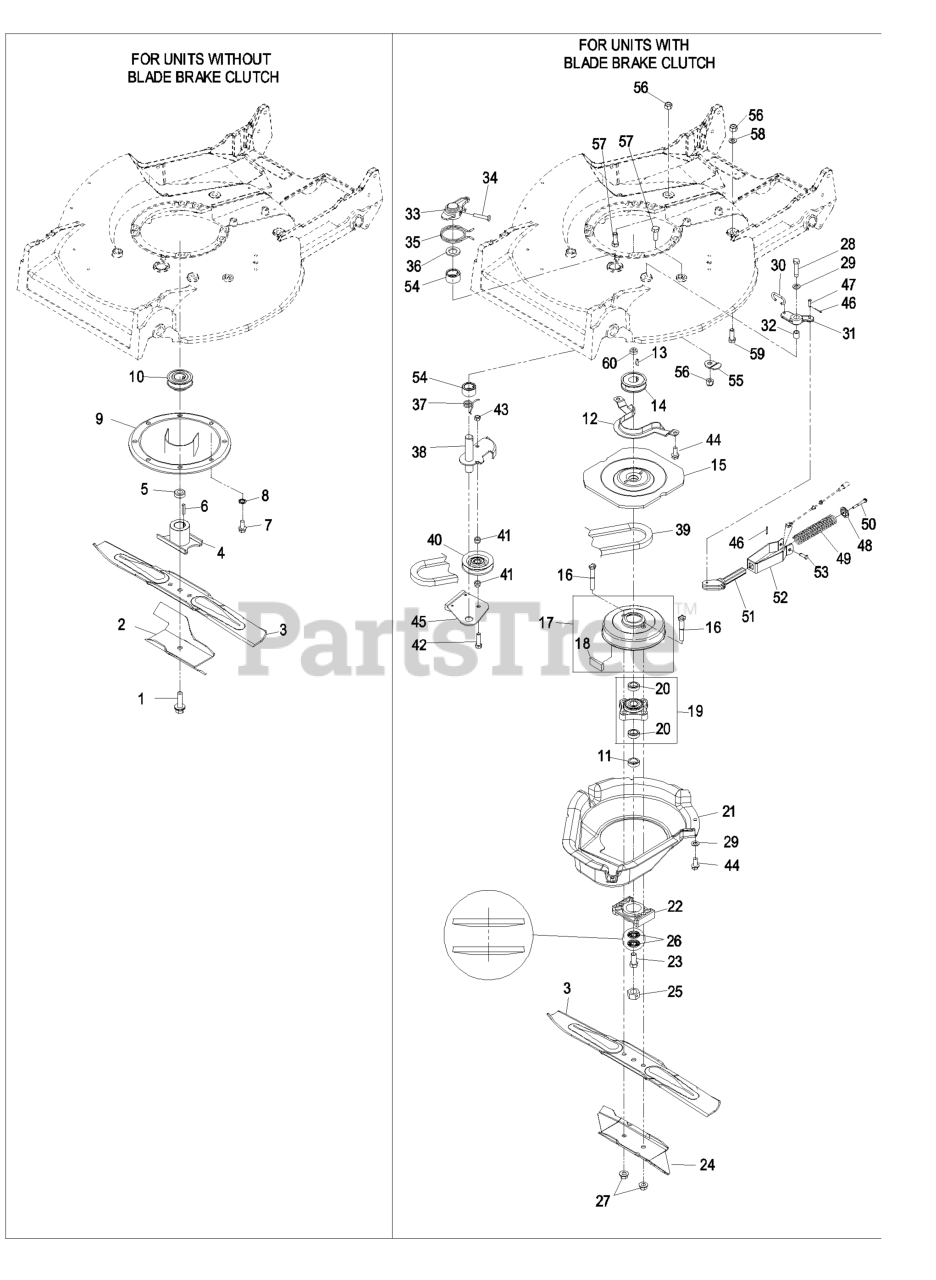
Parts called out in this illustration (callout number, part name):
2	STIFFENER-BLADE
3	BLADE-BAGGING, 21 INCH
4	RETAINER-BLADE
5	SPACER-RETAINER, BLADE
6	KEY-SQUARE
7	Screw-HWH 5/16-18 X 3/4 Tf
8	WASHER-LOCK, INTERNAL
9	PROTECTOR-CRANKSHAFT
10	PULLEY-DRIVER
11	SPACER-SHAFT, OUTPUT
12	BRACKET-GUIDE, BELT
13	KEY-WOODRUFF
14	PULLEY-DRIVER
15	FLYWHEEL-BBC
16	BOLT-BLADE
17	BRAKE DRUM ASM
18	DAMPENER-VIBRATION
19	HUB ASM
22	SPACER-BLADE
23	SCREW-HH
24	STIFFENER-BLADE
25	NUT-BLADE
26	WASHER-SPRING
27	Nut, Hex 3/8-24 Lock
28	SCREW-HH
29	WASHER-PLAIN
30	LINK-CONTROL
31	BELLCRANK
32	SLEEVE-BELLCRANK
34	SCREW-HH
35	SPRING-TORSION
37	SPRING-TORSION
38	ARM-IDLER
39	V-BELTNSP
41	SPACER-PULLEY, IDLER
42	SCREW-HH
43	NUT-LOCK, NI
44	Screw-HWH 5/16-18 X 3/4 Tf
46	PIN-COTTER
47	PIN-SPRING
48	RETAINER-SPRING
50	SCREW-HWHTF
51	GUIDE-SPRING
52	BRACKET-SPRING
53	PIN-CABLE
54	BEARING
55	SHIELD-RETAINER
56	NUT-LOCK, NI
57	SCREW-HH
58	WASHER-HARDENED
59	SCREW-HH
60	SPACER-PULLEY
